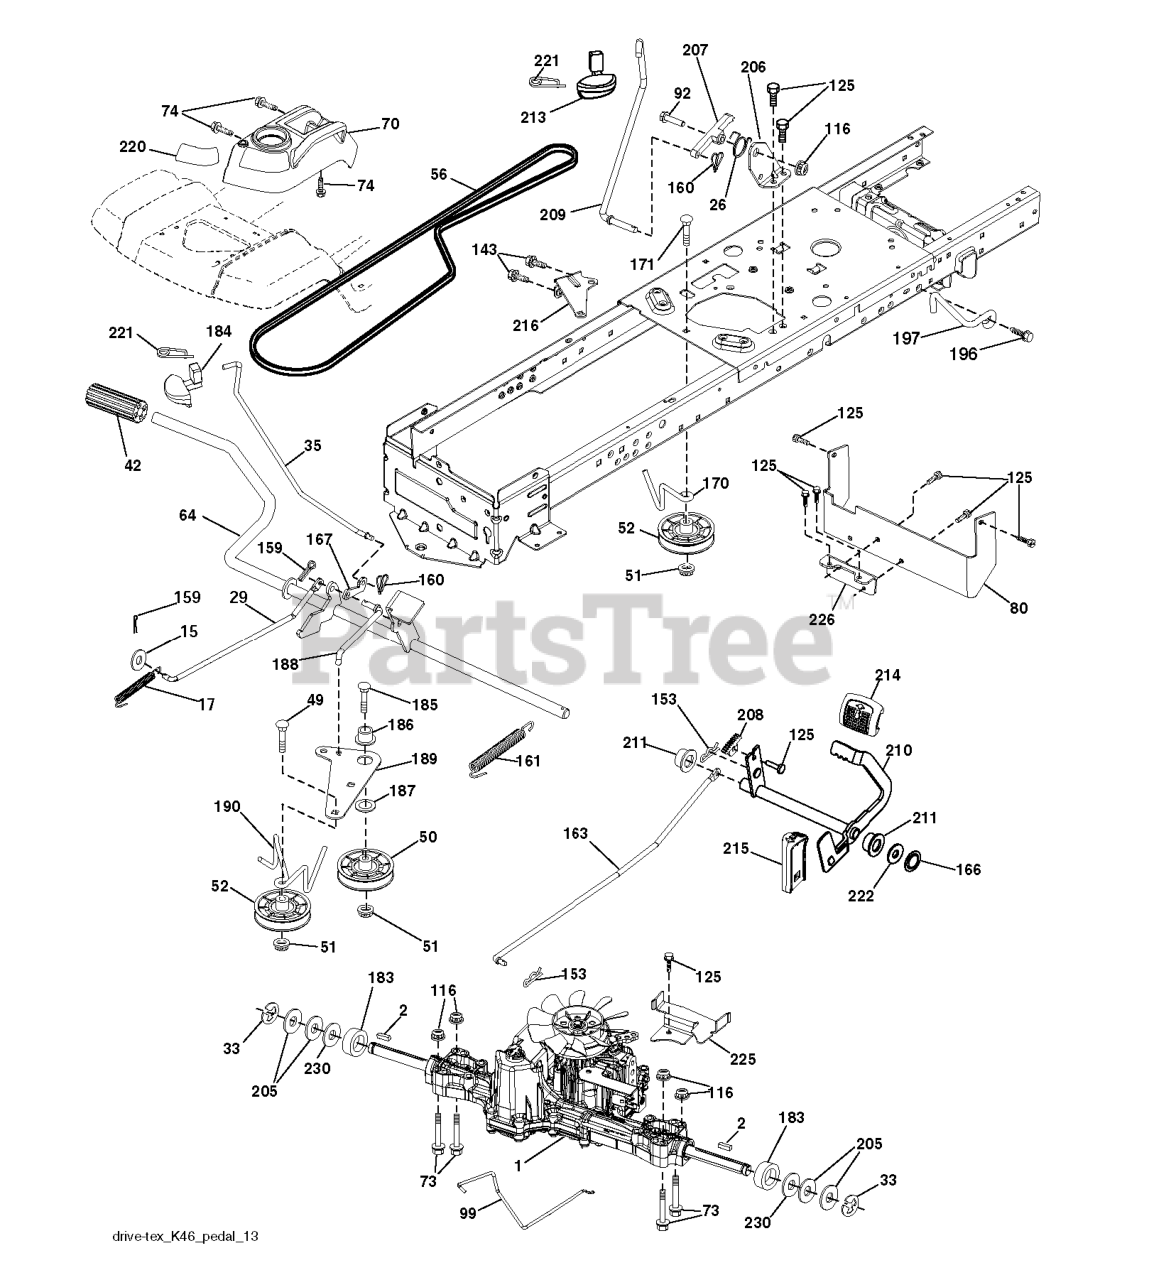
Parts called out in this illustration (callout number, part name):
2	SQUARE KEY
15	WASHER
17	SPRING.BRAKE.K46.GREEN
26	SPRING.RETURN.CRUISE
29	ROD.BRAKE.K46
35	ROD.BRAKE.PARKING.GT.H
42	PEDAL COVER T
50	IDLER.FLAT.910.OFFSET
51	NUT LOCK FLG 3/8-16 UNC
52	IDLER.V-GROOVE.910.OFFSET
56	V-BELT.MOWER.92.40.42/K46
64	SHAFT.ASM.PEDAL.BRK.CNTR
70	RP CONSOLE.ASM.PCH.W/TB
73	BOLT HEX 5/16-18 GR 5
74	SCREW.HI-LO.CONSOLE
80	STRAP TORQUE
92	BOLT
99	ROD.SPRING.BYPASS.K46.LT.Z
116	NUT LOCK HEX FLANGE 5/16-18
125	SCREW
143	Screw 5/16-18 x 1/2 Hex, Self Tapping 5/16-18 x 1/2
153	RETAINER M
159	COTTER PIN
160	RETAINER CLIP
161	SPRING, RETURN LT
163	ROD.CONTROL.PEDAL.K46
166	NUT.PUSH.625
167	LATCH.BRAKE.SPRING
170	KEEPER.V-IDLER.CENTER.
183	SPACER AXLE
184	HANDLE.PARKG.BRK.HUSQ X667
186	SPACER.RETAINER
187	WASHER 12/32X2X10GA
188	RP.LINK.CLUTCH.GROUND.DRIVE
189	BELLCRANK.GROUND.DRIVE.TEX.
190	KEEPER.BELLCRANK.DRIVE
196	SCREW 3/8-16X1
197	LINK.CLUTCH.ANIT-ROTAT
206	BRKT.MOUNT.LATCH.CRUIS
207	LATCH.CONTROL.CRUISE
208	GEAR.SECTOR.CONTROL.CR
209	ROD.CONTROL.CRUISE.GT.
210	ROCKER.ASM.PEDAL.CONTR
211	BEARING.NYLON
213	KNOB.CONTROL.CRUSIE.HU
214	PEDAL.FORWARD.PAD.TEX
215	PEDAL.REVERSE.TEX.GT.4
216	BRACKET.PULLEY.IDLER.W/TEX
220	REFLECTOR.RH.TEX GT
221	RETAINER.SPRING.CLIP.H
222	WASHER 21/32 X 1-1/4 X 10 GA.
225	KEEPER.BELT.TRANSAXLE.K46
226	BRACKET.MOUNT.TORQUE.K46.TLT
230	WASHER.HARDENED
